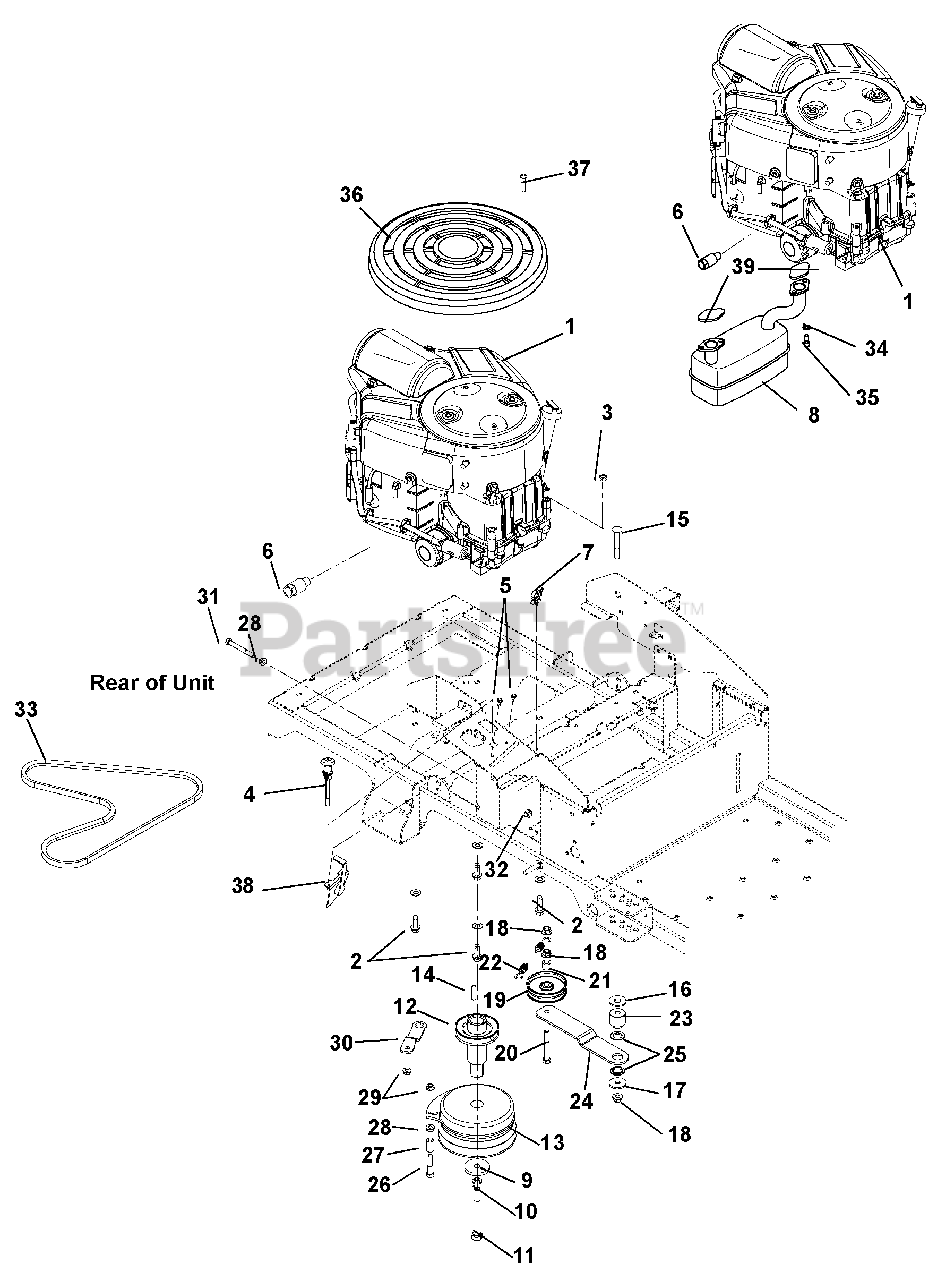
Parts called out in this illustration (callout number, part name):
1	Engine, 16HP V-Twin CE (915327)
1	Engine, 18HP V-Twin CE (915328)
2	Screw, Tapping .38-16 x 1.25 Hex Washer Head
3	Nut, Locking Jam .375-16 (915327)
4	Cable, Choke
5	Screw, Tapping 10-24 x .50 Hex Washer Head
6	Oil Drain
7	Wire Clip (for .25" hole)
8	Muffler, Twin Briggs
9	Washer, Flat Steel .469 x 2.00 x .25
10	Washer, Locking .44 x .109 Regular
11	Bolt, Hex .44-20 x 4.50 Grade 8
12	Weldment, Crankshaft Extension
13	Clutch, 105 FT*LB MONO Pole
14	Key, Square .25 x 1.25 x .25 SAE 8630 or SAE 1035
15	Bolt, Round Head Square Neck .38-16 x 2.75
16	Washer, Flat Steel .563 x 1.38 x .109
17	Washer, Flat Steel .406 x 1.375 x .135
18	Nut, Locking Nylon Flange .38-16
19	Pulley, Engine Clutch
20	Bolt, Hex .38-16 x 2.75
21	Bushing, Sleeve .391 x .688 x .52
22	Spring, Extension
23	Spacer, Ground Drive Idler
24	Idler Arm, Ground Drive
25	Bushing, Idler Arm
26	Screw, Cap .31-18 x 1.75
27	Spacer, Rubber 5/16 ID x 1.0
28	Nut, Spin Lock Flange .312-18
29	Nut, Locking Top Flange .31-18
30	Bracket, Clutch Stop
31	Bolt, Hex .31-18 x 2.75
32	Nut, Locking Nylon Flange .31-18
33	V-Belt, HA-RAW Edge Laminated
34	Washer, Locking .31 x .078 Regular
35	Capscrew .31-18 x .75 S/HD
36	Guard, Briggs Engine
37	Screw, 8-16 x .87
38	Cable, Throttle
39	Gasket, Muffler Courage Twin
